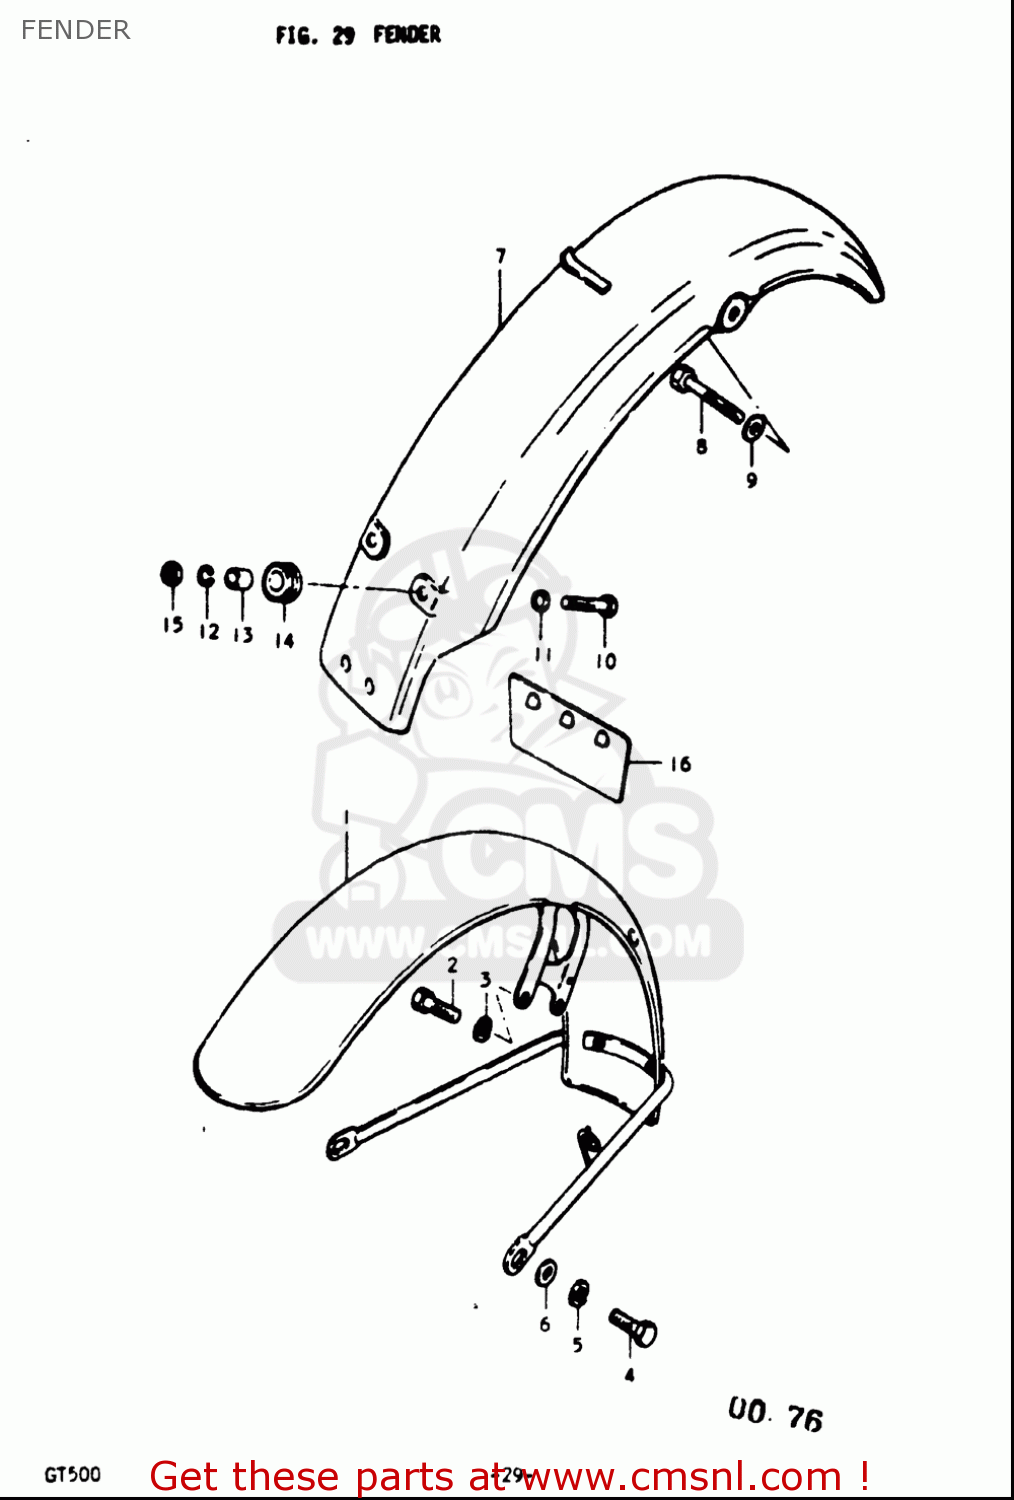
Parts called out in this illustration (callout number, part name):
1	FENDER ASSY,FR
2	BOLT
3	WASHER,LOCK
4	BOLT
5	WASHER,LOCK
6	WASHER
8	BOLT
9	WASHER,LOCK
10	BOLT
11	WASHER(6.5X24X1.6)
12	WASHER,LOCK
13	SPACER(6.5X10X7)
14	CUSHION
15	NUT
16	GUIDE,RR FENDER MUD
